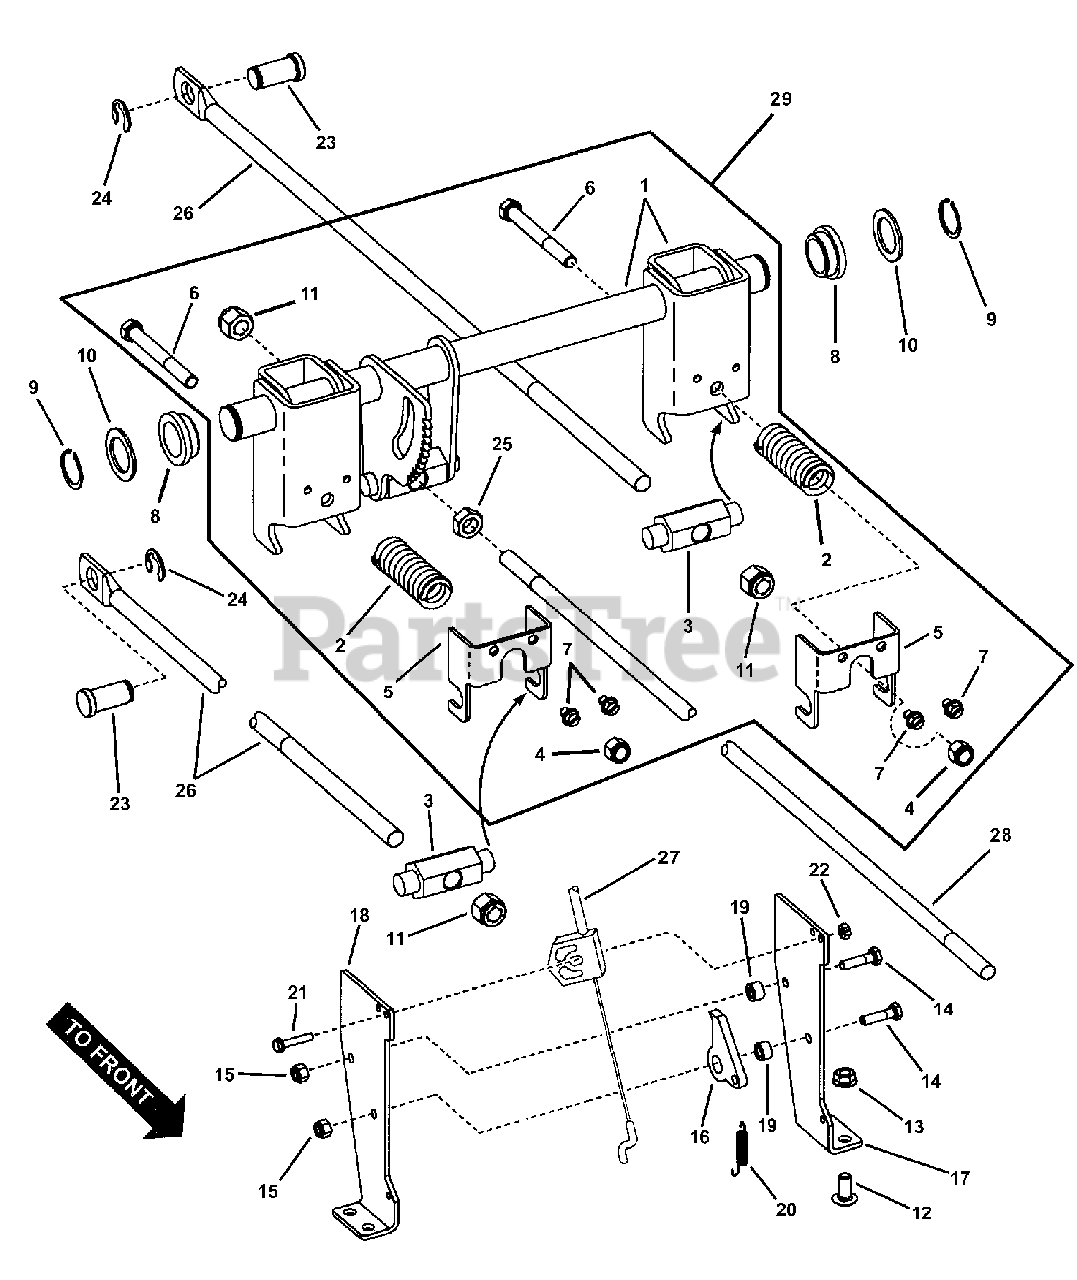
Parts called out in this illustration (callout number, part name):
1	BRAKE SHAFT ASSEMBLY, Rear CVT
2	SPRING, CVT Brake
3	BRAKE SWIVEL, w/.531 Thru Hole
4	NUT, Hex Nyloc, 3/8-16
5	BRACKET, Swivel Retainer, Used on Model 85668
5	BRACKET, Swivel Retainer, Used on Model 85632 & 85903
6	CAPSCREW, Hex Head, 3/8-16 x 3-1/4 GR 5
7	SCREW, Hex Washer Self-Tap, 1/4-20 x 3/8
8	BEARING, 1 I.D.
9	RING, 1.00 Dia. External Retaining
10	BUSHING, 14 Ga Machine
11	NUT, Hex Nyloc, 1/2-20
12	CARRIAGE BOLT, 5/16-18 x 3/4 GR 5
13	NUT, Hex Flange Lock, 5/16-18 GR 5
14	CAPSCREW, Hex Head, 1/4-20 x 1 GR 5
15	NUT, Hex Nyloc, 1/4-20
16	PAWL, Park Brake
17	BRACKET, LH Park Brake Pawl Pivot, Used on Model 85668
17	BRACKET, LH Park Brake Pawl Pivot, Used on Model 85632 & 85903
18	BRACKET, RH Park Brake Pawl Pivot, Used on Model 85668
18	BRACKET, RH Park Brake Pawl Pivot, Used on Model 85632 & 85903
19	SPACER, Park Brake
20	SPRING, Pawl Return
21	SCREW, Hex Washer Self-Tap, #10-32 x 1
22	NUT, Hex Center Lock, #10-32
23	PIN, Brake Anchor
24	RETAINING RING, 5/8 Shaft
25	NUT, Hex Jam, 1/2-20 GR 5 or B
26	BRAKE ROD, Rear CVT
27	CABLE, Parking Brake
28	ROD, Lower CVT Brake, 1/2-20 Thread, Both Ends
29	BRAKE ASSEMBLY, Utility Vehicle (Includes Ref. Nos. 1 thru 7), Used on Model 85668
29	BRAKE ASSEMBLY, Utility Vehicle (Includes Ref. Nos. 1 thru 7), Used on Model 85632 & 85903
